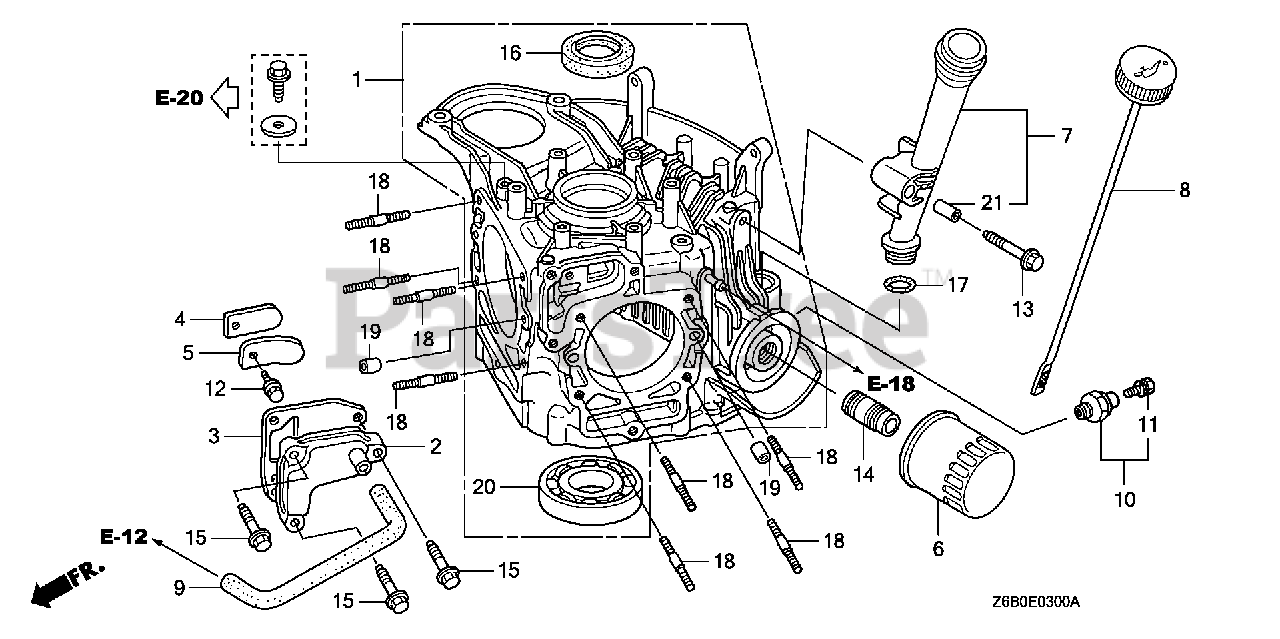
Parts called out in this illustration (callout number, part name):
1	CRANKCASE ASSY. (810)
2	COVER, BREATHER
3	GASKET, BREATHER COVER
4	PLATE, VALVE
5	STOPPER, VALVE
6	FILTER, OIL
6	FILTER, OIL (FILTECH TOYO ROKI) (SOLD IN MULTIPLES OF 30)
6	FILTER, OIL (HONEYWELL) (SOLD IN MULTIPLES OF 30)
6	FILTER, OIL (DENSO)
7	EXTENSION, OIL FILLER
8	GAUGE, OIL LEVEL
9	TUBE, BREATHER
12	BOLT, FLANGE (5X10) Use from Engine SN 2327377.
13	BOLT, FLANGE (6X45)
14	HOLDER, OIL FILTER
15	BOLT, FLANGE (6X25) Use up to Engine SN 2056819.
16	OIL SEAL (35X52X8)
17	O-RING (22.5X2.2) Use from Engine SN 1257295.
18	BOLT 2, STUD (8X28)
19	PIN A, DOWEL (8X14)
20	BEARING, RADIAL BALL (6207)
21	COLLAR, EXTENSION
